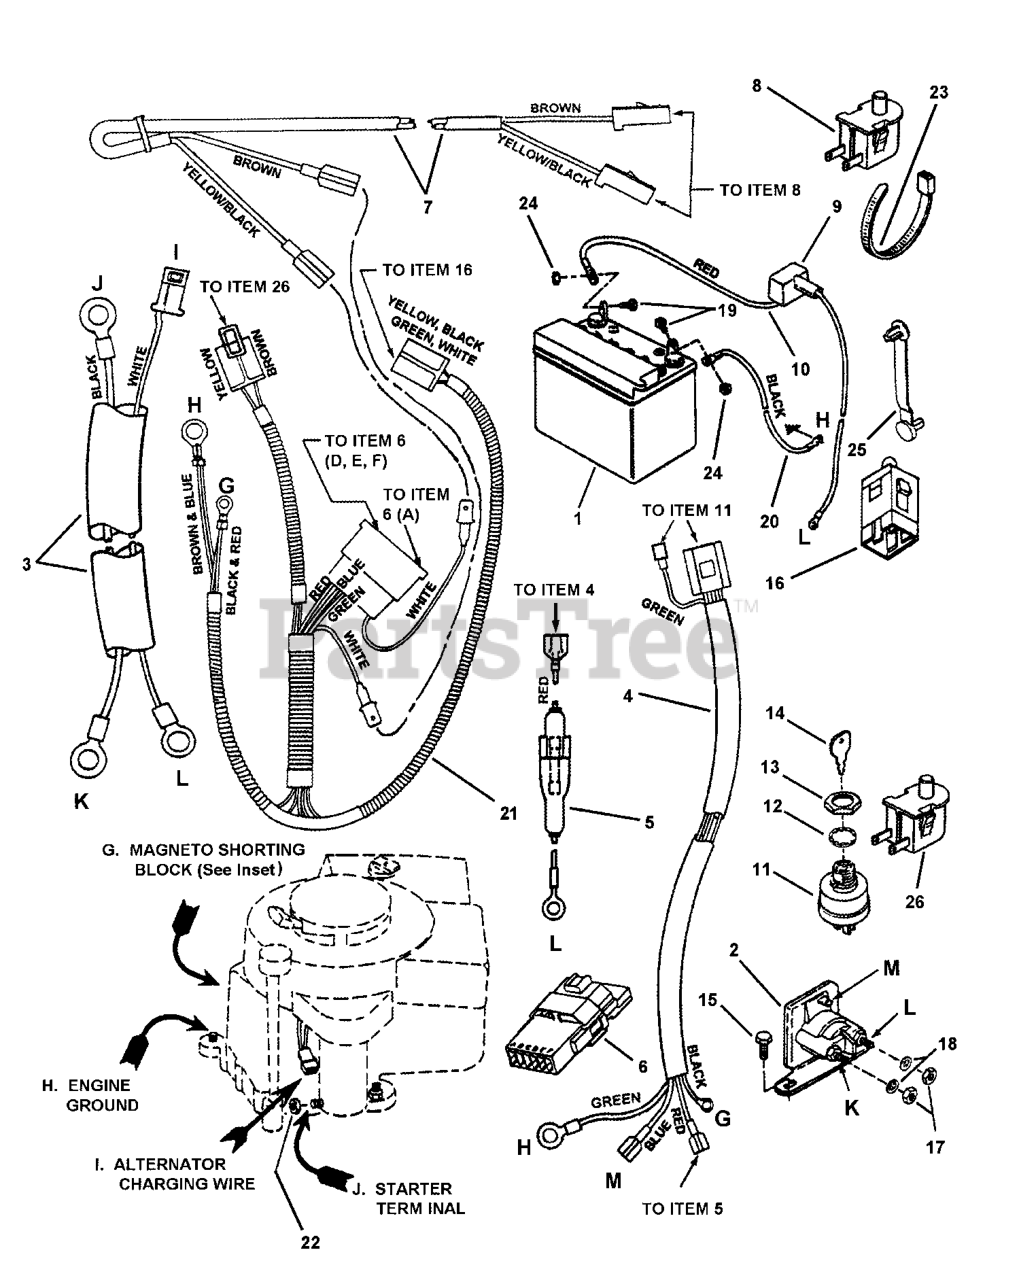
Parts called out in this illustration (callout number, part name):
1	BATTERY, 12V 140CCA L Terminal
2	SOLENOID, Super-Trombetta
3	HARNESS, Starter Wiring (Briggs Engines)
4	HARNESS, Ignition Wiring (Briggs Engines)
5	HOLDER, Fuse (Includes Fuse)
6	INTERLOCK MODULE, Briggs
7	HARNESS (Deck Interlock Wiring)
8	SWITCH, Deck Interlock (NO)
9	COVER, Battery Cable
10	WIRE, Positive (Red, 17" long)
11	SWITCH, Ignition, 4 Terminal, Indak
12	WASHER, 5/8" Internal Tooth Lock
13	NUT, 5/8-32 Hex
14	IGNITION KEY, Pair
15	SCREW, 1/4-20 x 1/2" Hex Washer Self-Tap
16	SWITCH, Operator Presence Control (OPC) Traction (NC/NO)
17	NUT, 1/4-20 Hex, GR 5 or B
18	WASHER, 1/4" Internal Tooth Lock
19	SCREW, 1/4-20 x 5/8" Hex Head Cap. GR 5
20	WIRE, Negative, Black (15" long)
21	HARNESS, Operator Presence Control (OPC) Wire
22	NUT, 1/4-20 Hex, GR 5 or B
23	CABLE TIE, 7"
24	NUT, 1/4-20 Hex Center Lock, GR 5 or B
25	CABLE TIE
26	SWITCH, Seat, Push Button (NC)
